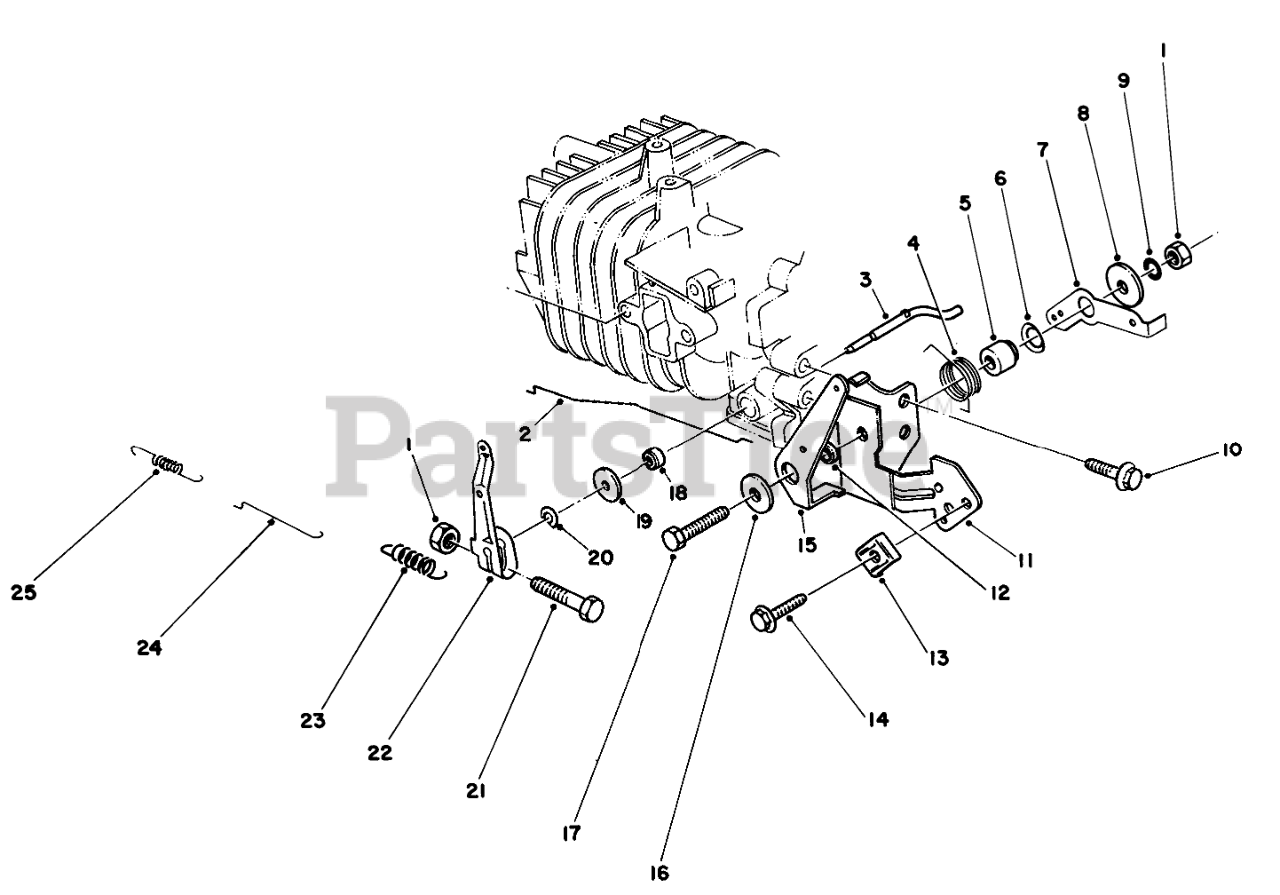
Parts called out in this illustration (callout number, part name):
2	CHOKE ROD
3	Shaft-Govemor
4	SPRING-CHOKE LEVER
5	Gov Lever Spacer
6	Washer-Gov. Spring Lever
7	GOV SPRING LEVER
7	LEVER-SPRING, GOVERNOR
8	WASHER
9	LOCKWASHER
11	BRACKET-THROTTLE, CONTROL
12	SPACER-CHOKE LEVER
13	CLAMP
15	LEVER-CONTROL, CHOKE
16	WASHER
18	SEAL-OIL
19	WASHER
20	E-RING
22	Lever-Throttle Control
22	GOVERNOR ARM
23	GOVERNOR SPRING
23	SPRING-GOVERNOR
24	ROD-CARBURETOR
25	SPRING
